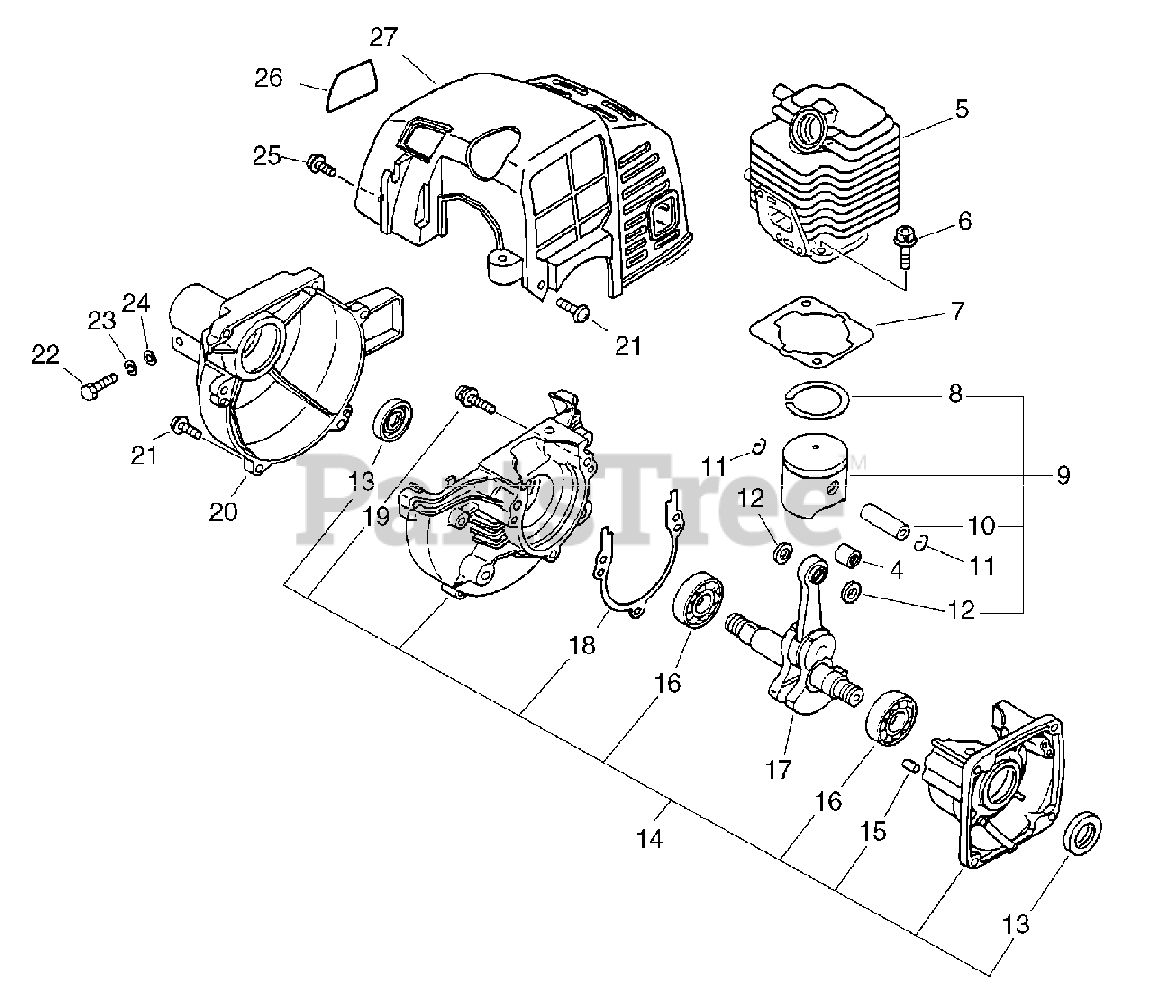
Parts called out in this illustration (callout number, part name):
4	Bearing,Needle 8
6	Bolt, H.S. 5*22
7	Gasket, Cyl. Base
8	Ring, Piston
9	Piston Kit
10	Pin, Piston
11	Circlip, Piston Pin
12	Spacer, Piston Pin
14	Crankcase Kit
15	Pin, Dowel
16	Bearing Ball
17	Crankshaft,Asm
18	Gasket, Crankcase
19	Bolt, H.S. 5*28
20	Cover, Fan (BS)
21	Screw 4*16
22	Bolt 5*25
23	Washer, Spring 5
25	Screw 4*12
26	Label, Model
27	Cover, Cylinder
